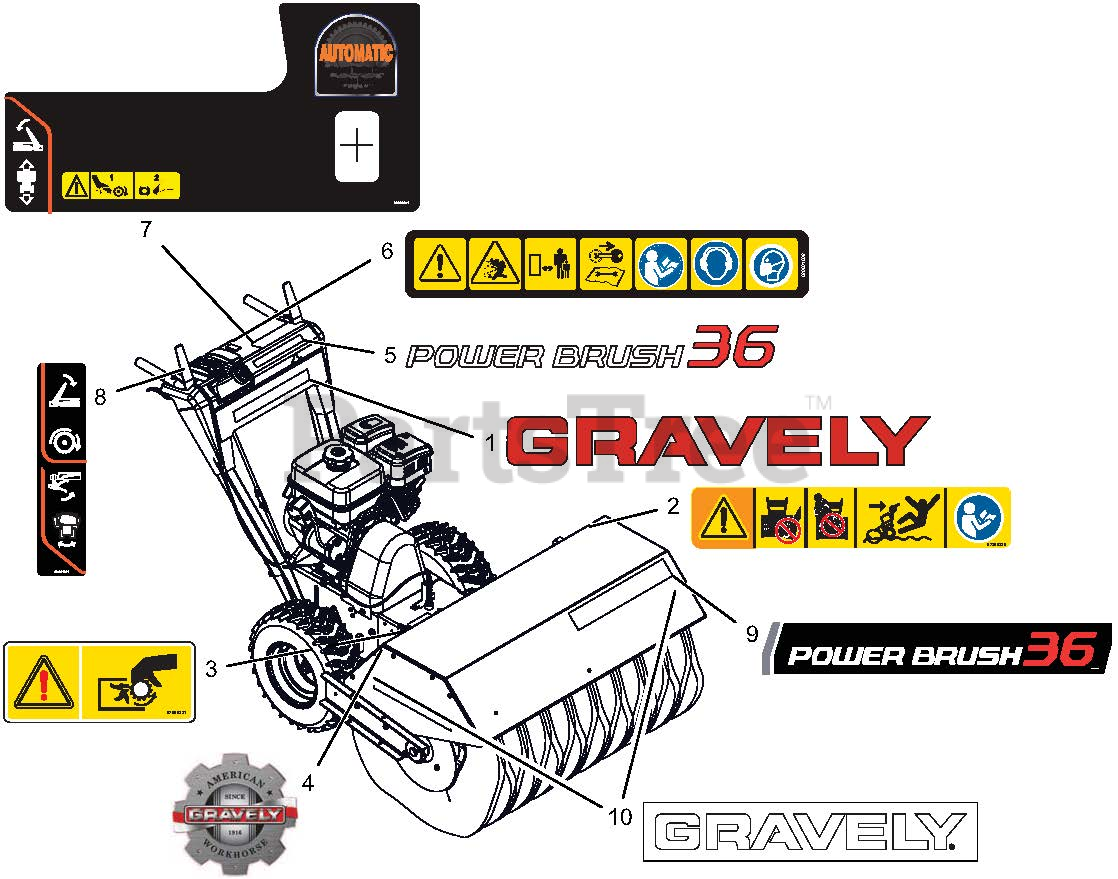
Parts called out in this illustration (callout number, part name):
1	DECAL,GRAVELY,RED,13"
2	DECAL, DANGER -POWER BRUSH-CE
3	DECAL, PTO WARNING
4	DECAL, GRAVELY HERITAGE-LARGE
5	DECAL,POWER BRUSH 36,GRAVELY
6	DECAL, SAFETY, DASH, BRUSH
7	DECAL,CNTRL,LRG BRUSH,LH,FRCTN
8	DECAL,CONTROL,BRUSH,RH
9	DECAL,POWER BRUSH 36,GRAVELY
10	DECAL, 13.5" GRAVELY LOGO
